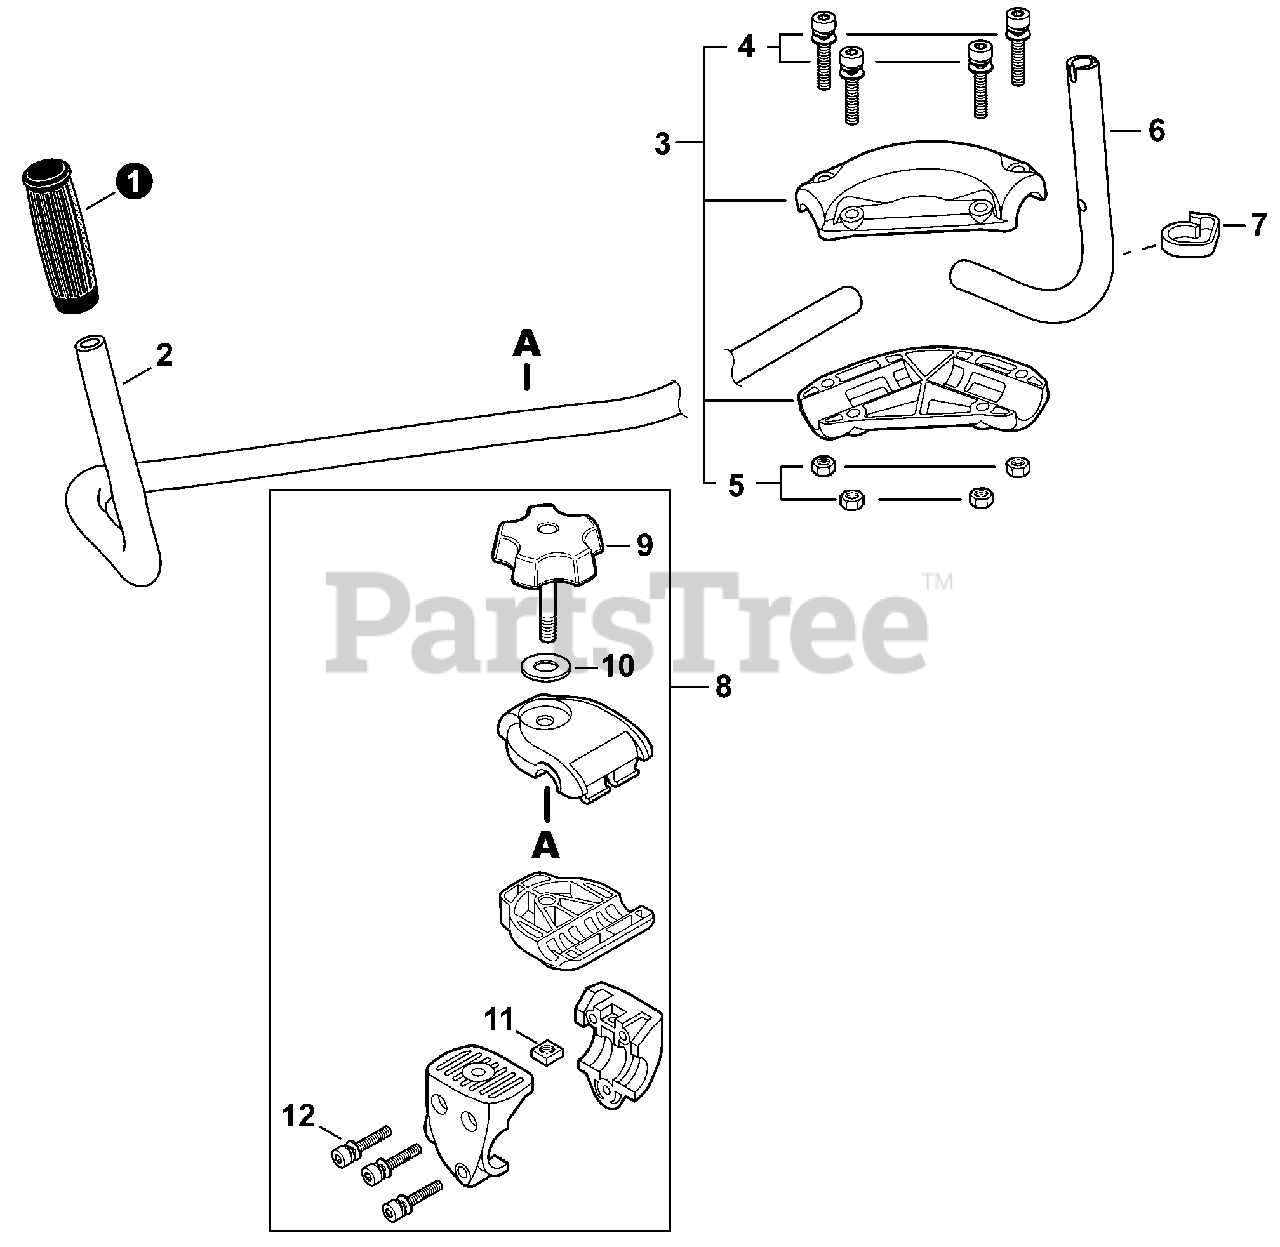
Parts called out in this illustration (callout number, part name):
1	GRIP, HANDLE
2	HANDLEBAR, LEFT
3	BRACKET KIT, HANDLEBAR
4	BOLT 5×22
5	NUT M5
6	HANDLEBAR, RIGHT
8	MOUNTING KIT, HANDLEBAR
9	KNOB, SCREW M8
10	WASHER 8
11	NUT 8×1.25
12	BOLT 5×30
